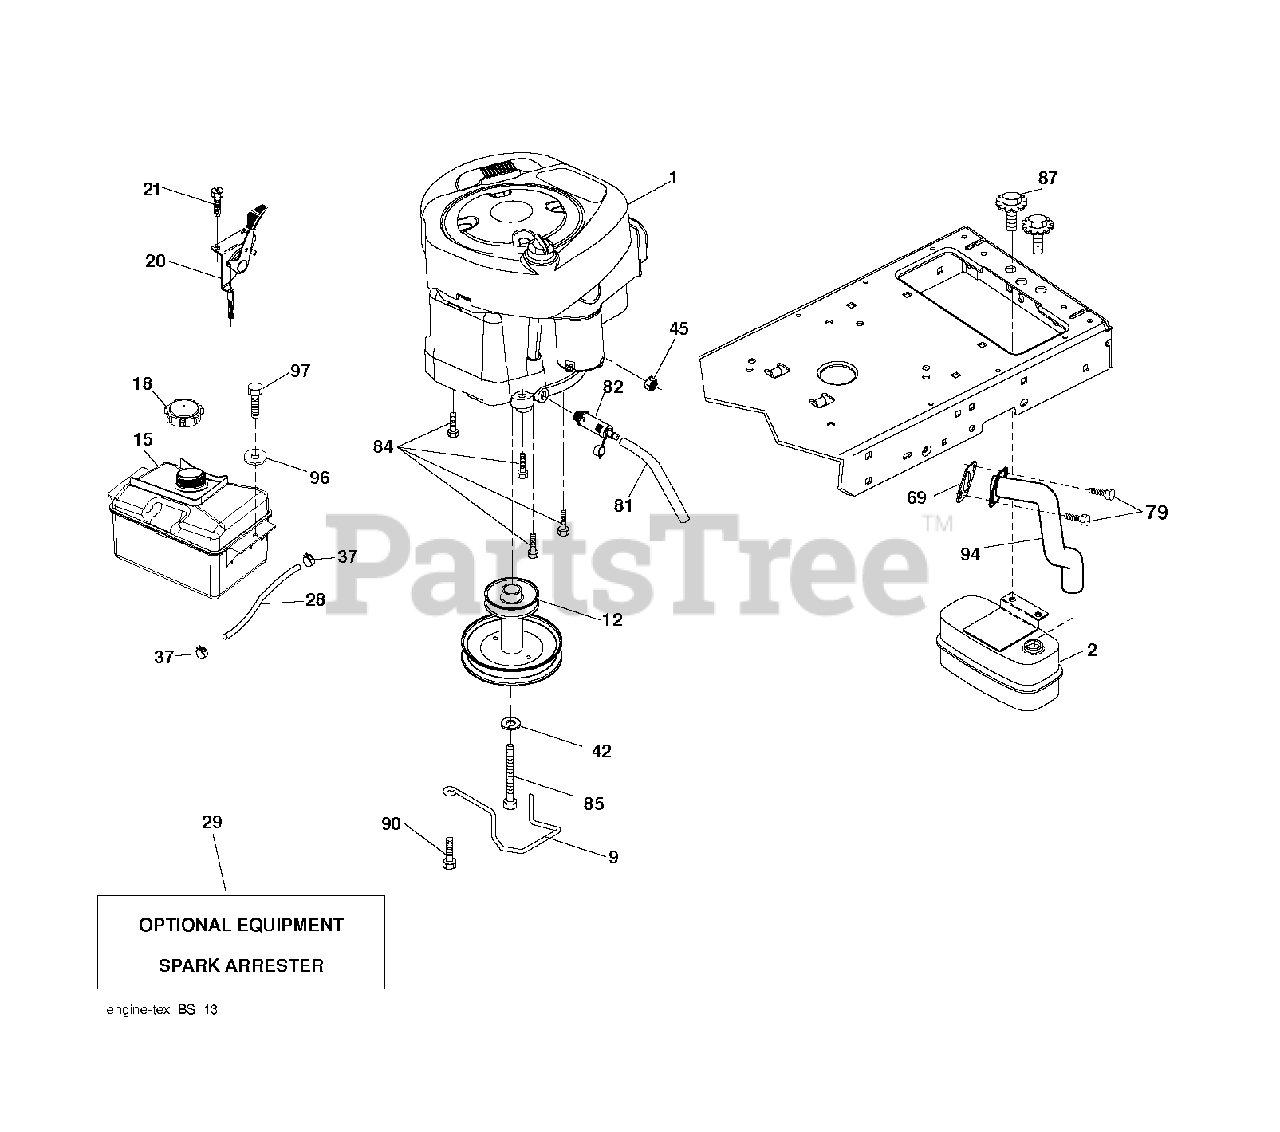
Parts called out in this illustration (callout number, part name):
2	MUFFLER.SINGLE.CYL.KOHL/B&S
9	KEEPER.BELT.ENGINE.3.25
12	PULLEY ENGINE
15	TANK FUEL FRT 1.5 GAL
18	FUEL CAP
20	CONTROL.TH/CK.C.
21	SCREW.#10 X 0.750.BOS THREAD
28	LINE.FUEL.20
29	ARRESTER SPARK (OPTIONAL)
37	HOSE CLAMP
42	LOCKWASHER
45	NUT
69	REPL BY 532 27 22-93
79	SCREW.SOCKET HD.5/16-1
81	TUBE, DRAIN OIL ASM.
82	PLUG DRAIN OIL EASY
84	SCREW.3/8-16
85	BOLT HEX 7/16-20X4-1/4"
87	BOLT, 5/16-18 X 1 3/4
90	SCREW 3/8-16X1
94	EXHAUST.TUBE.B&S.
97	SCREW HEXWSHR 1/4-20X3/4
